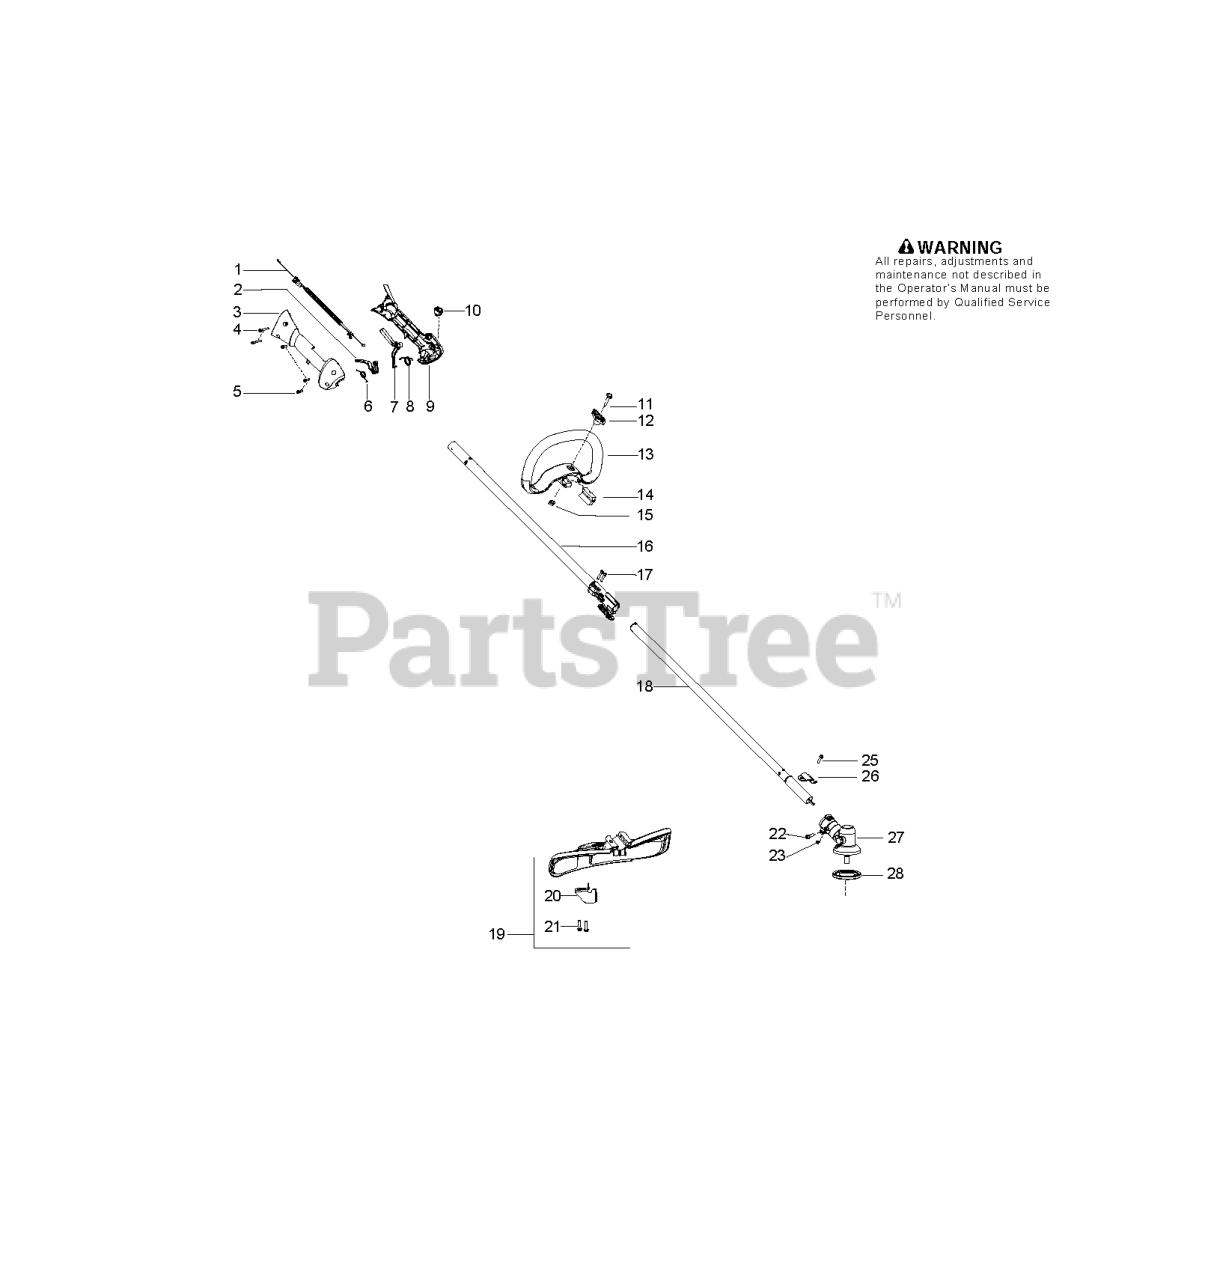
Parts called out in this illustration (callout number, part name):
1	ASSY-CABLE WIRE HARNESS
2	TRIGGER THROTTLE
3	HOUSING-THROTTLE RH
5	SCREW M4 X 1.75 PT 16MM
6	SPRING TRIGGER
7	THROTTLE LOCKOUT
8	SPRING LOCKOUT
9	HSG THROTTLE LH
10	KIT SWITCH
16	KIT-DRIVESHAFT UPPER (INCL. 17
18	KIT DRIVESHAFT LOWER LDX
19	KIT COBI SHIELD
20	Limiter - Line
22	SCREW - CARB. ADAPTOR
25	SCREW 1/4-20 X 7/8 (TAP
26	BRACKET SHIELD STRAIGHT SHAFT
27	ASSY GEARBOX
28	DRIVE DISC
